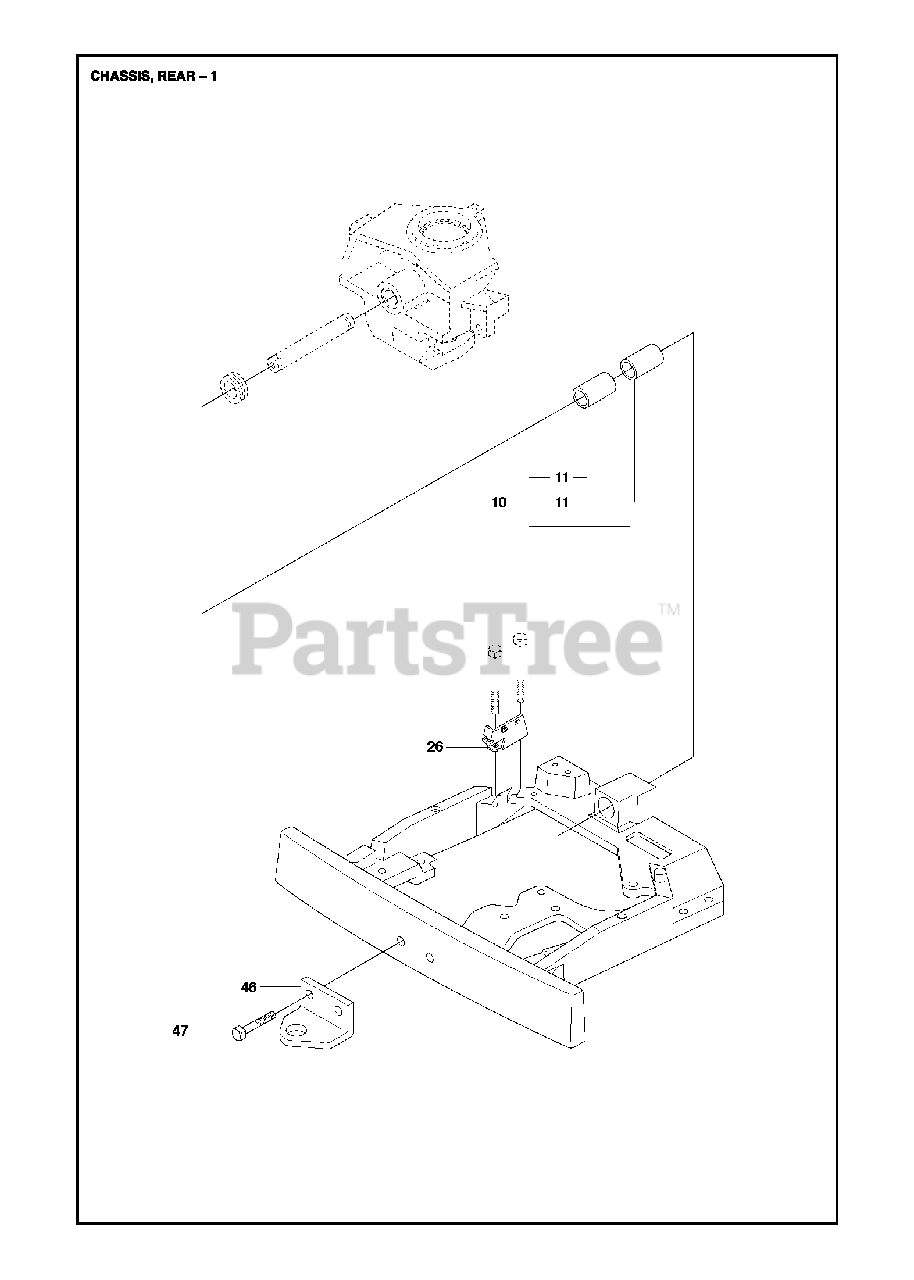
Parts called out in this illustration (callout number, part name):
11	BUSHING
46	DRAW RING
47	SCREW M10X25
